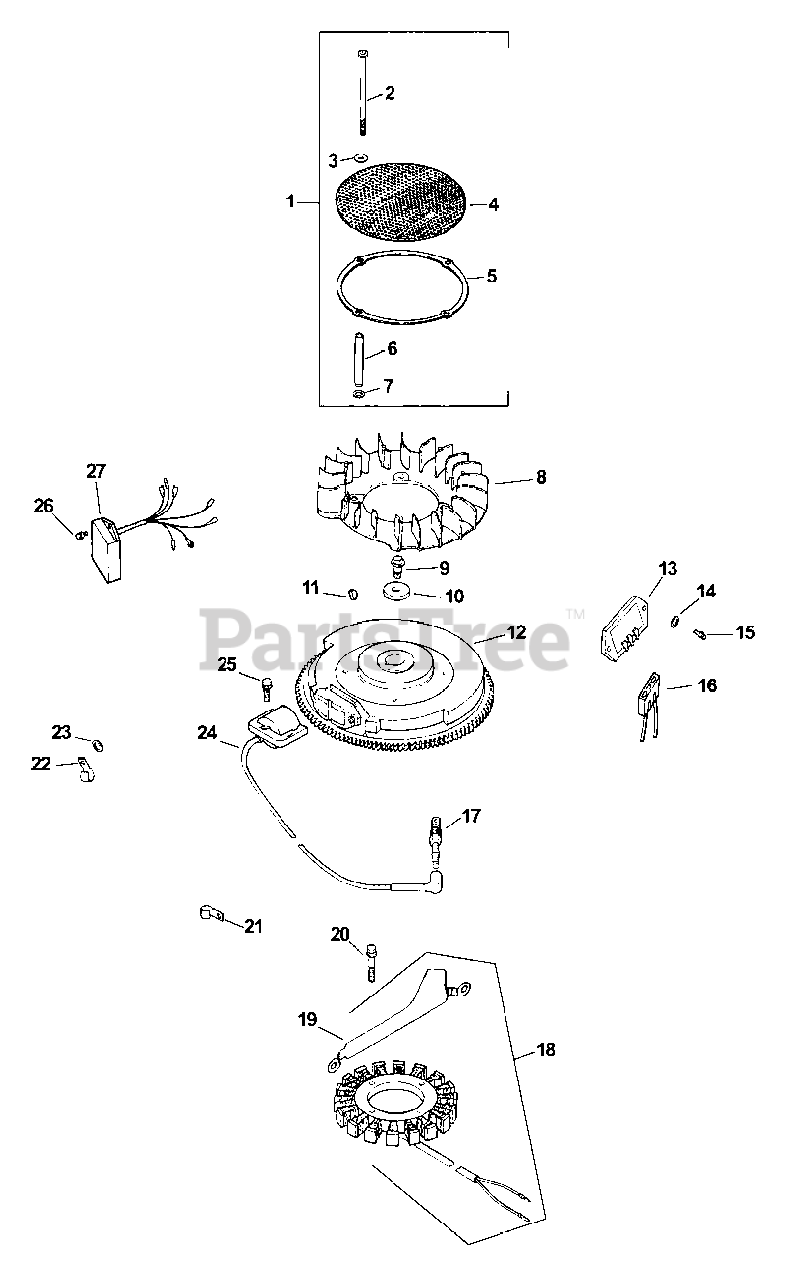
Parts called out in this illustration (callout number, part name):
1	Chopper Screen Kit
2	Hex Head Screw (M6 x 1.0 x 100)
3	Plain Washer (5/16")
4	Grass Screen
5	Support Ring
6	Grass Screen Spacer
7	Spring Washer
8	Fan
9	Hex Flange Screw (M10 x 1.5 x 46)
10	Plain Washer (3/8")
12	Flywheel
13	Regulator - Rectifier
14	Plain Washer (3/16")
15	Phillips Head Screw (11-16 x 7/8")
16	Connector (3 Contact)
17	Spark Plug
18	15 amp Stator Kit
19	Stator Wire Bracket
20	Hex Cap Screw (M5 x .8 x 25)
21	Cable Clip
23	Plain Washer (1/4")
24	Ignition Module
25	Hex Flange Screw (M5 x .8 x 20)
26	Screw (M4 x .7 x 10)
27	Speed Advance Module
